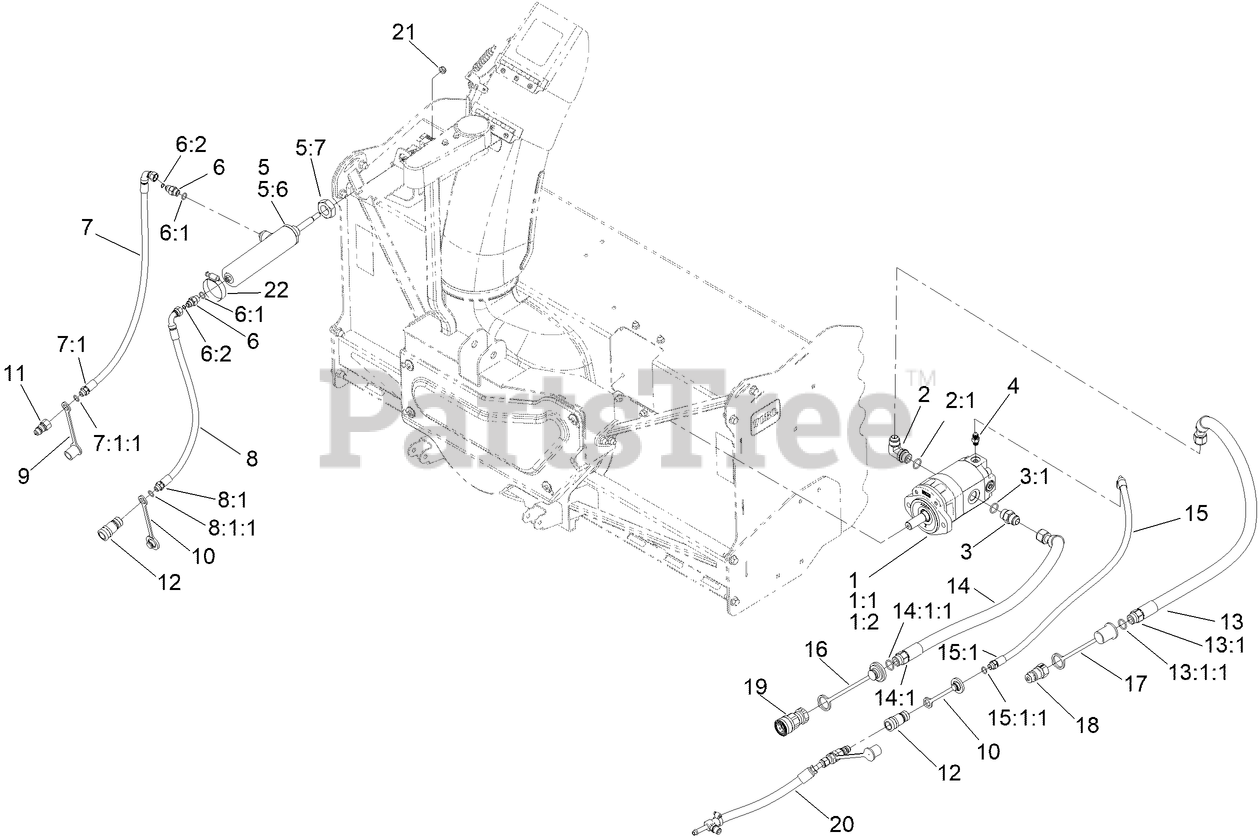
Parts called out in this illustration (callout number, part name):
1	MOTOR-HYDRAULIC
1:1	MOTOR SEAL KIT
1:2	RELIEF VALVE- 3335PSI
2	FITTING-ELBOW, 90 DEG
2:1	O-RING
3	FITTING-STRAIGHT
3:1	O-RING
4	FITTING-STRAIGHT
5	CYLINDER
5:6	KIT-SEAL, CYLINDER
5:7	NUT-HEX JAM
6	FITTING-STRAIGHT
6:2	O-RING
7	HOSE-HYD
7:1	FITTING-STRAIGHT, RIGID
7:1:1	O-RING
8	HOSE-HYD
8:1	FITTING-STRAIGHT, RIGID
8:1:1	O-RING
9	CAP-DUST
10	PLUG-DUST
11	NIPPLE-DISCONNECT, QUICK
12	COUPLER-DISCONNECT, QUICK
13	HOSE-HYD
13:1	FITTING-STRAIGHT
13:1:1	O-RING
14	HOSE-HYD
14:1	FITTING-STRAIGHT
14:1:1	O-RING
15	HOSE-HYD
15:1	FITTING-STRAIGHT, RIGID
15:1:1	O-RING
16	PLUG-QUICK CONNECT
17	CAP-CONNECT, QUICK
18	DISCONNECT-QUICK , MALE
19	QUICK COUPLER-FEMALE
20	CASE DRAIN KIT
21	NUT-HEX
22	CLAMP-HOSE
